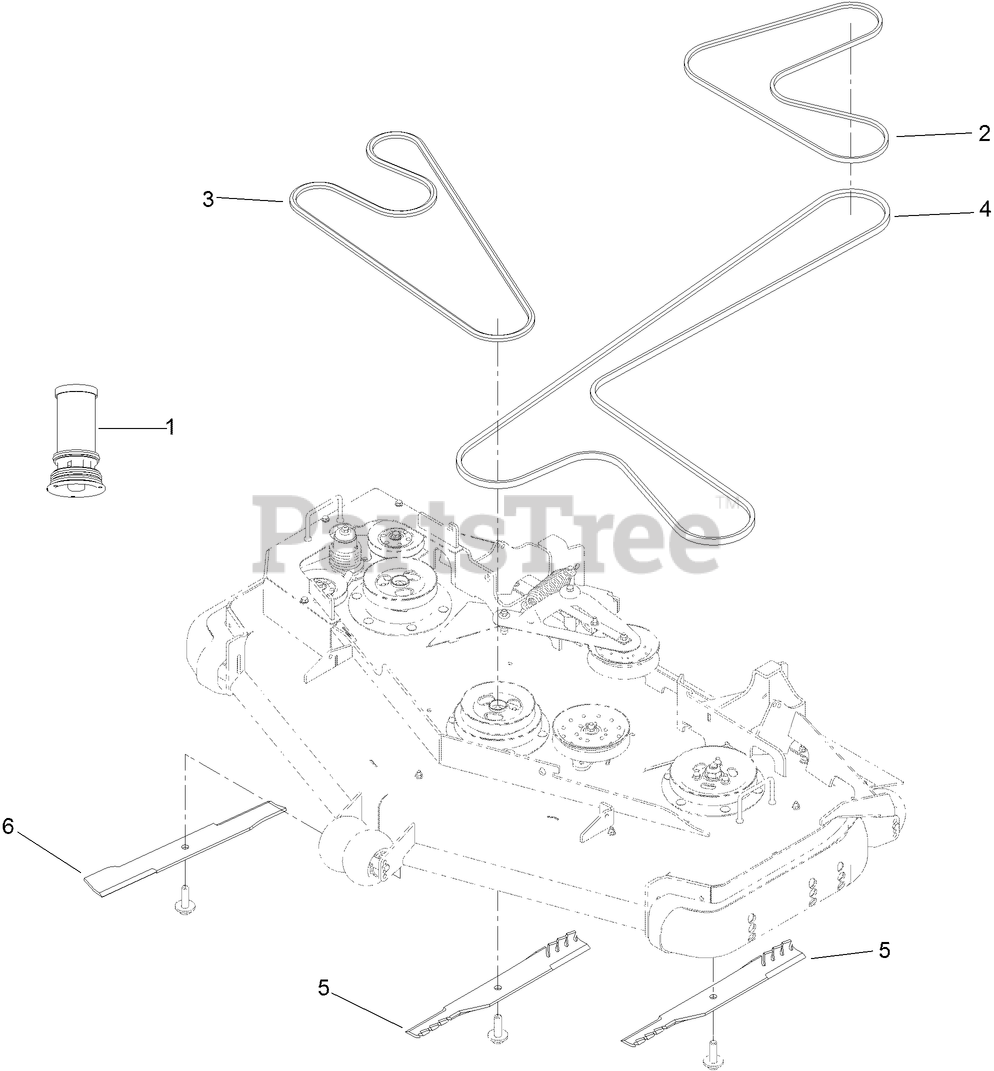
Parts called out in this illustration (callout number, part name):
1	FILTER-HYDRO
2	BELT
5	BLADE-ATOMIC, 20.5IN
6	BLADE-ROTARY, 20.5IN LOW FLOW
